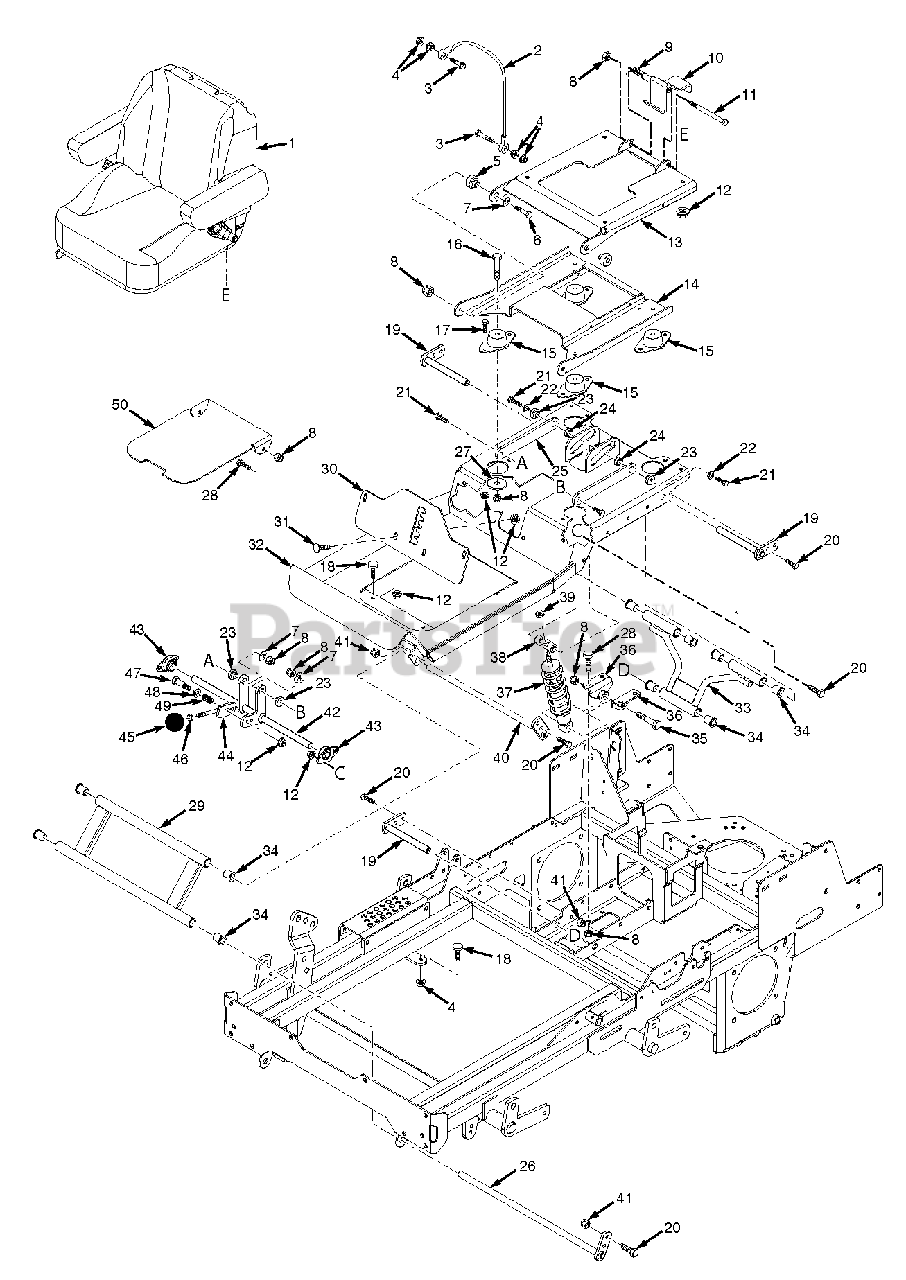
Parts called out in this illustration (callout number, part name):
1	Seat Assembly
2	Cable, Seat Stop
3	Bolt, Hex Head 1/4-20 x 1-1/4"
4	Nut, Serrated Flange 1/4-20
5	Sleeve, Seat Base Mount
6	Bolt, Hex Head 3/8-16 x 2"
7	Flatwasher, 3/8-.391 x .938 x .105
8	Nut, Elastic Stop 3/8-16
9	Spring, Seat Latch
10	Latch Weldment, Seat
11	Bolt, Hex Head 3/8-16 x 6"
12	Nut, Serrated Flange 5/16-18
13	Seat Plate Weldment
14	Seat Mounting Plate Weldment w/Decal
15	Isolator, Seat
16	Bolt, Hex Head 3/8-16 x 2-1/4"
17	Bolt, Hex Head 5/16-18 x 3/4"
18	Bumper, Rubber
19	Shaft Weldment, Rear Op. Platform Pivot
20	Bolt, Hex Head 5/16-18 x 1"
21	Bolt, Hex Head 3/8-16 x 1-1/2"
22	Lockwasher, 3/8" Spring
23	Bushing
24	Bearing
25	Link, Suspension Seat Tensioner
26	Pin Weldment, Op Platform Lower Pivot
27	Flatwasher, 3/8-.406 x 2.25 x .188
28	Bolt, Hex Head 3/8-16 x 1"
29	Suspension Pivot Assembly, Front
30	Bracket, Suspension Adjustment w/Decal
31	Bolt, Carriage 5/16-18 x 1"
32	Seat Mounting Base Weldment w/Decal
33	Suspension Pivot Assembly, Rear
34	Bearing
35	Bolt, Hex Head 3/8-16 x 2-3/4"
36	Mount Weldment, Shock
37	Shock Absorber, Suspension
38	Mount, Suspension Shock
39	Nut, Elastic Stop 3/8-24 Grade 8
40	Pin Weldment, Op Platform Upper Pivot
41	Nut, Elastic Stop 5/16-18
42	Pivot Weldment, Suspension Tensioner
43	Bearing, Self Align 5/8" ID
44	Adjustment Lever, Suspension
46	Nut, Jam 3/8-16
47	Bolt, Shoulder 3/8 x 1"
47	Bolt, Shoulder 3/8 x 3/8"
48	Flatwasher, 3/8-.406 x .812 x .065
49	Spring
50	Cover, Foot PLate
